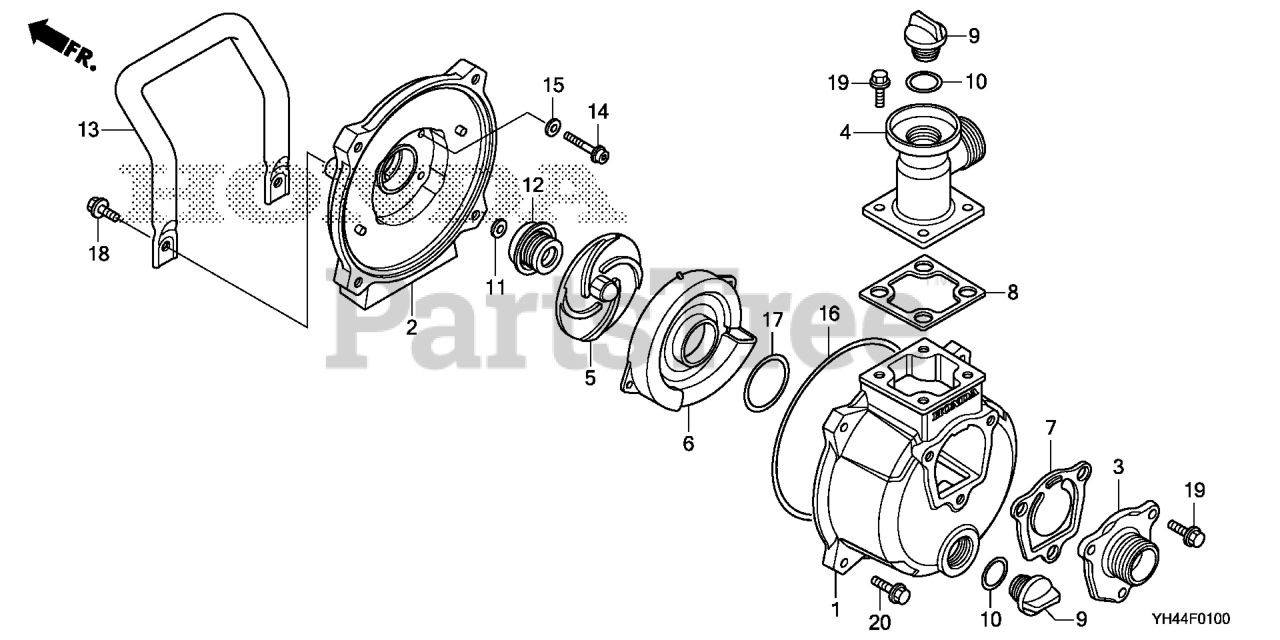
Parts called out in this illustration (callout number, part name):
2	COVER, CASING
3	INLET (NPT1)
4	OUTLET (NPT1)
6	CASE, VOLUTE
7	VALVE, IN.
8	GASKET, OUTLET
9	CAP, FILLER
10	O-RING (23.7X3.5)
11	SHIM, ADJUSTER
12	SEAL ASSY., MECHANICAL
14	BOLT, FLANGE SOCKET (5X35)
15	WASHER, SEALING (5MM)
16	O-RING (140X3.5)
17	O-RING (36.5X5.7)
18	BOLT, FLANGE (6X14)
19	BOLT, FLANGE (6X20)
20	BOLT, FLANGE (6X25)
